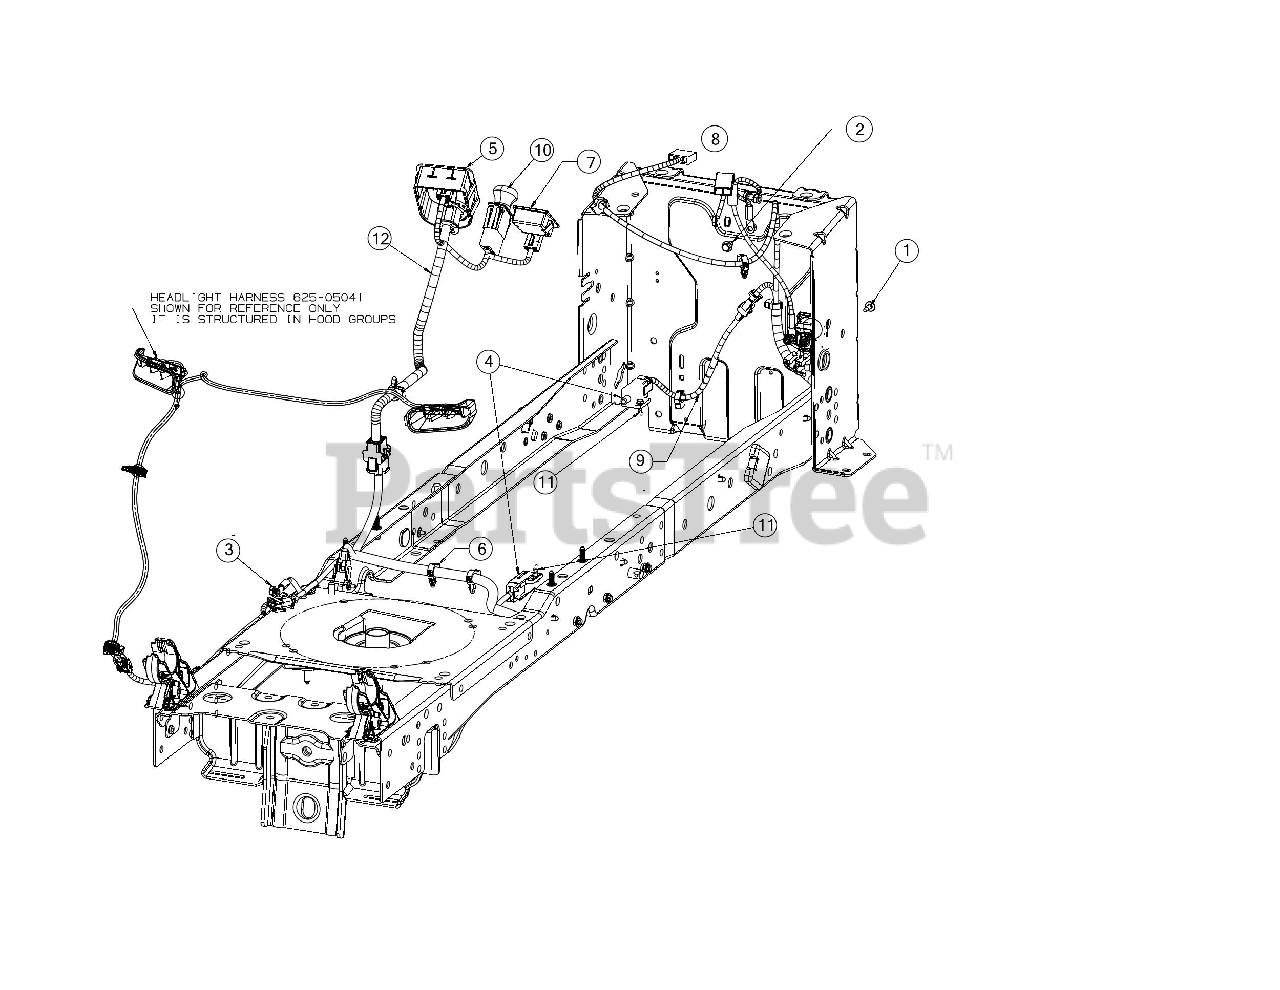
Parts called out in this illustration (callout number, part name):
1	SCREW M6-1 X .625
2	SCREW 1/4-20X.625
3	HEX NUT 1/4-20
4	INTERLOCK SWITCH (NO/NC)
5	IGNITION MODULE SWITCH RMC (ELC PTO WHTE)
6	DASH HARNESS
7	HOUR METER SERVICE MINDER
8	REVERSE HARNESS
9	CLUTCH HARNESS 11"
10	PTO SWITCH
11	SHOULDER SCREW
